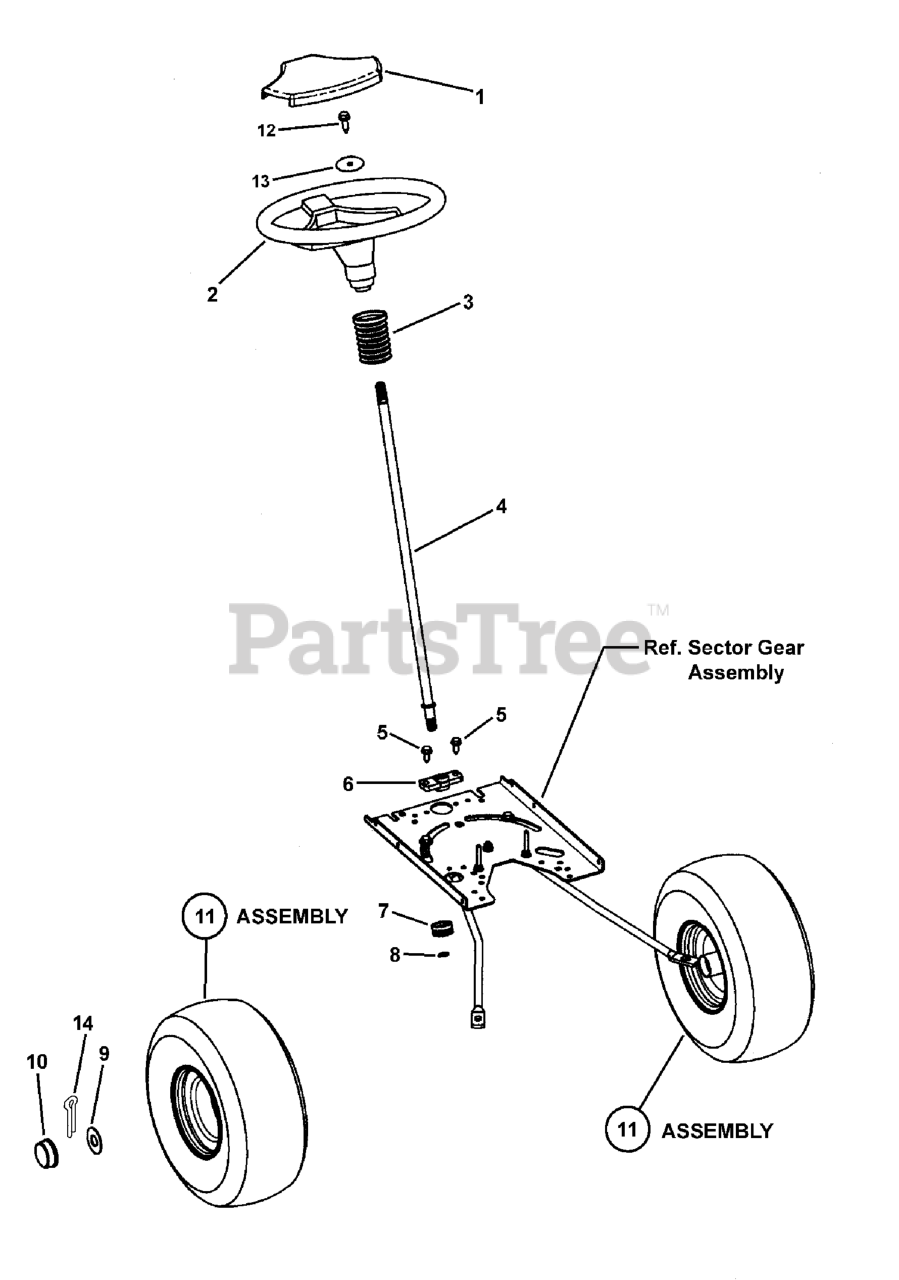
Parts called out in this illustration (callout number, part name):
1	COVER, INTEGRA
2	STEERING WHEEL (HARD RIM)
3	BELLOWS - STEERING POST
4	STEERING POST (22.56" LONG)
5	CAPSCREW 5/16-18
6	BEARING - LOWER
7	GEAR PINION
8	SNAP RING, 0.543"ID
9	FW, 1.862X .765 X 16GA
10	HUB CAP
11	ASSY, Wheel & Tire, 15 x 6.00-6 (inc. 4 items shown below)
12	THD FORMING HES HD SCREW, 1 X 1/4-20 STEP TAPER
13	WASHER, FLAT .34, 1.20 11G
14	PIN, Cotter, 3/4
